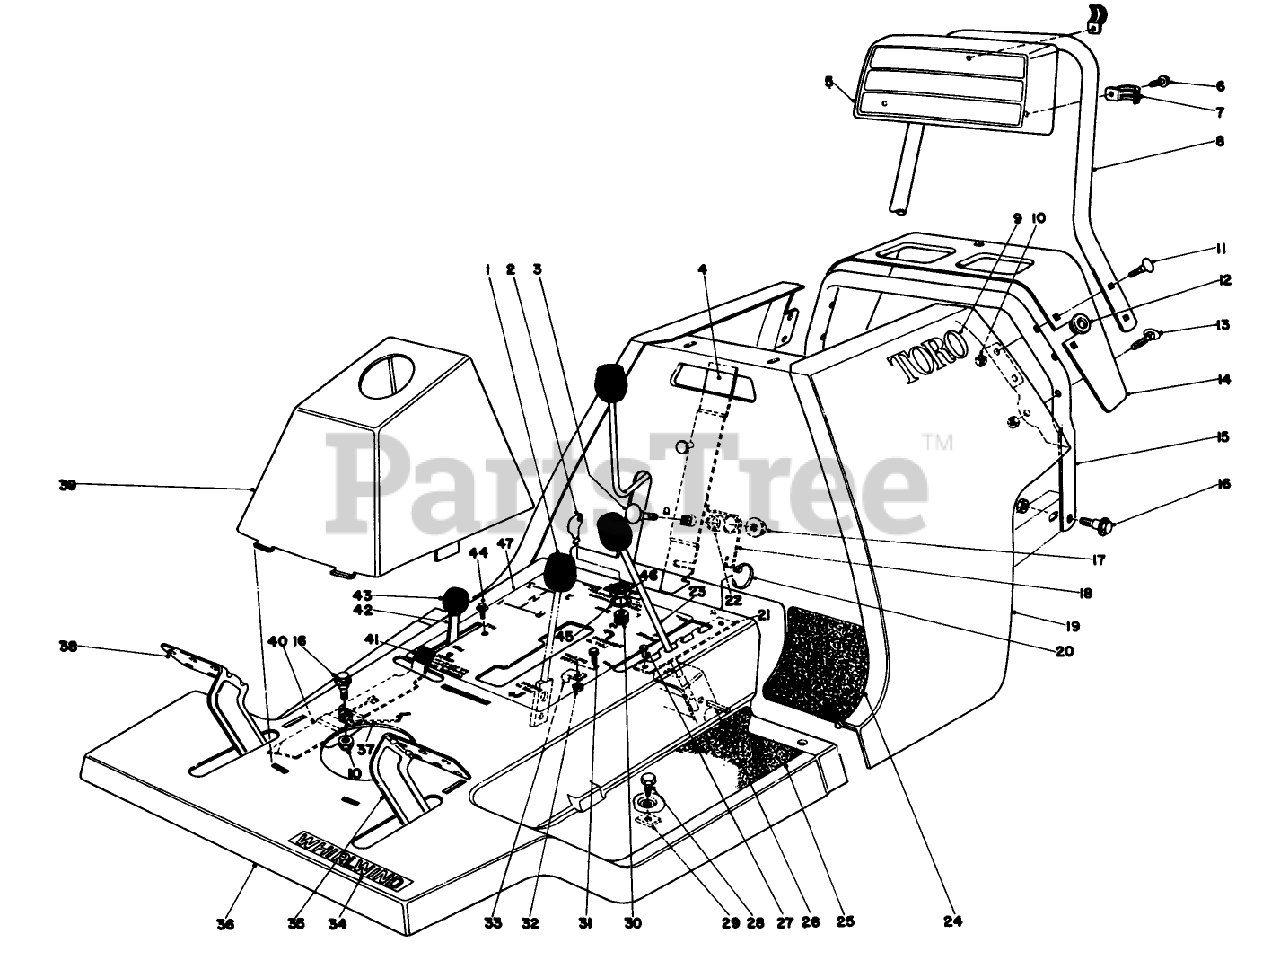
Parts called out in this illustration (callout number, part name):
3	BOLT-CARR
6	Screw
7	Clamp Conduit
9	TORO LOGO DECAL
10	NUT-LOCK, CONE
11	BOLT-CAR
16	SCREW-SHOULDER
17	NUT-HF
20	TIE-CABLE
28	SCREW-HH
29	NUT-TINNERMAN
32	NUT-KEPS
36	Body Front (Incl. Ref. #39 40)
37	SPRING-PARKING BRAKE
41	TIP-PARKING BRAKE
42	Throttle Control
45	WASHER-LOCK
46	NUT-HH
